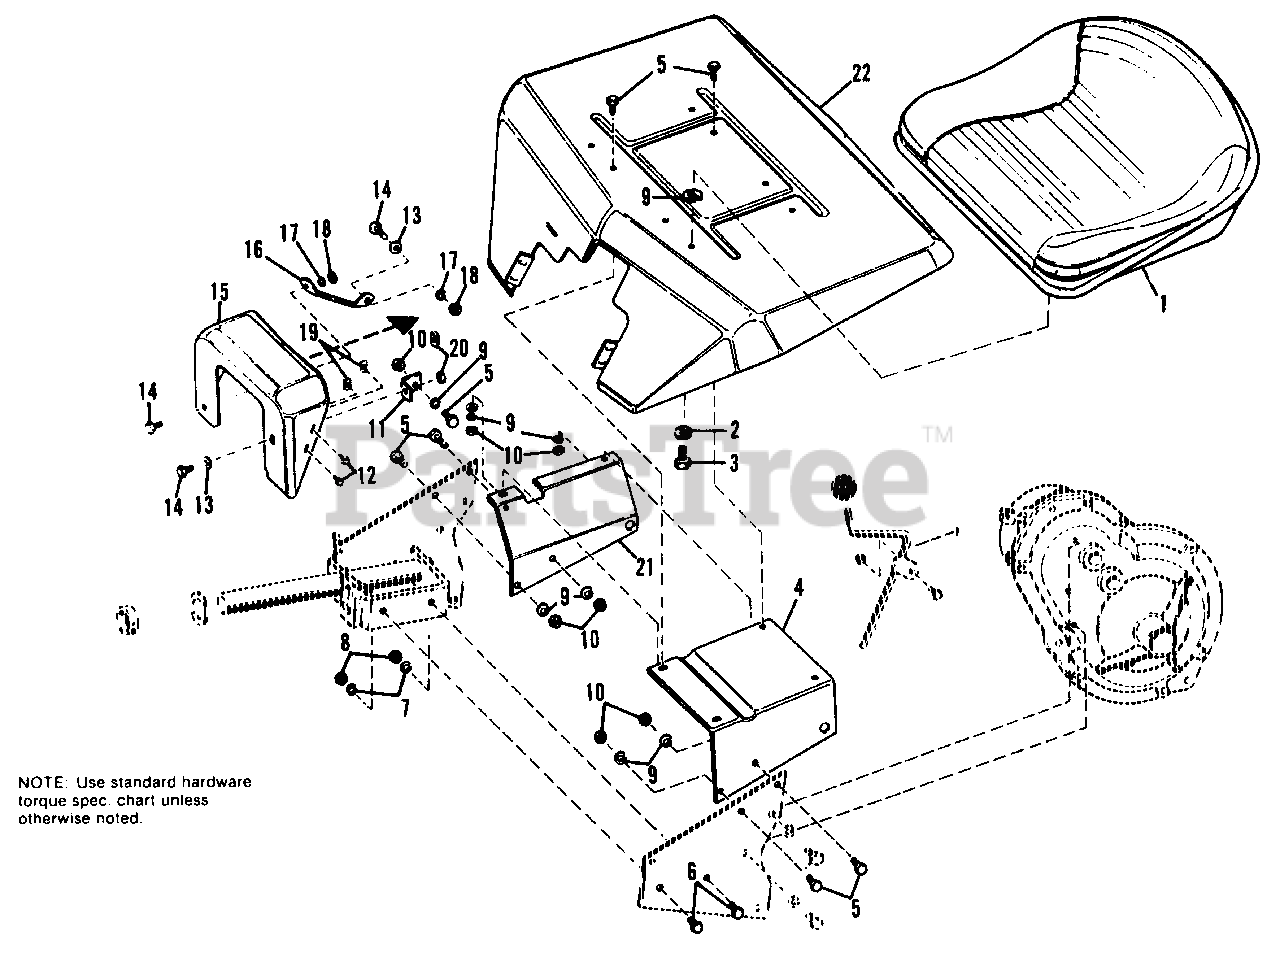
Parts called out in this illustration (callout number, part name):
2	WASHER, Plain, 5/16
3	CAPSCREW, Hex Hd., 5/16-18 x 7/8
4	BRACKET, L.H.
5	CAPSCREW, Hex Hd., 5/16-18 x 3/4
6	CAPSCREW, Hex Hd., 7/16-14 x 1
7	LOCKWASHER, 7/16
8	NUT, Hex, Full, 7/16-14
9	LOCKWASHER, 5/16
10	NUT, Hex, Full, 5/16-18
11	CLIP, Cover
12	SCREW, Hex, Self Tapping, #10 x 1/2
13	WASHER, Plain, 1/4
14	CAPSCREW, Hex Hd., 1/4-20 x 5/8
15	COVER, Seat Support
16	BRACE, Cover
17	LOCKWASHER, 1/4
18	NUT, Hex, Full, 1/4-20
20	NUT, Retainer
22	SUPPORT, Seat
